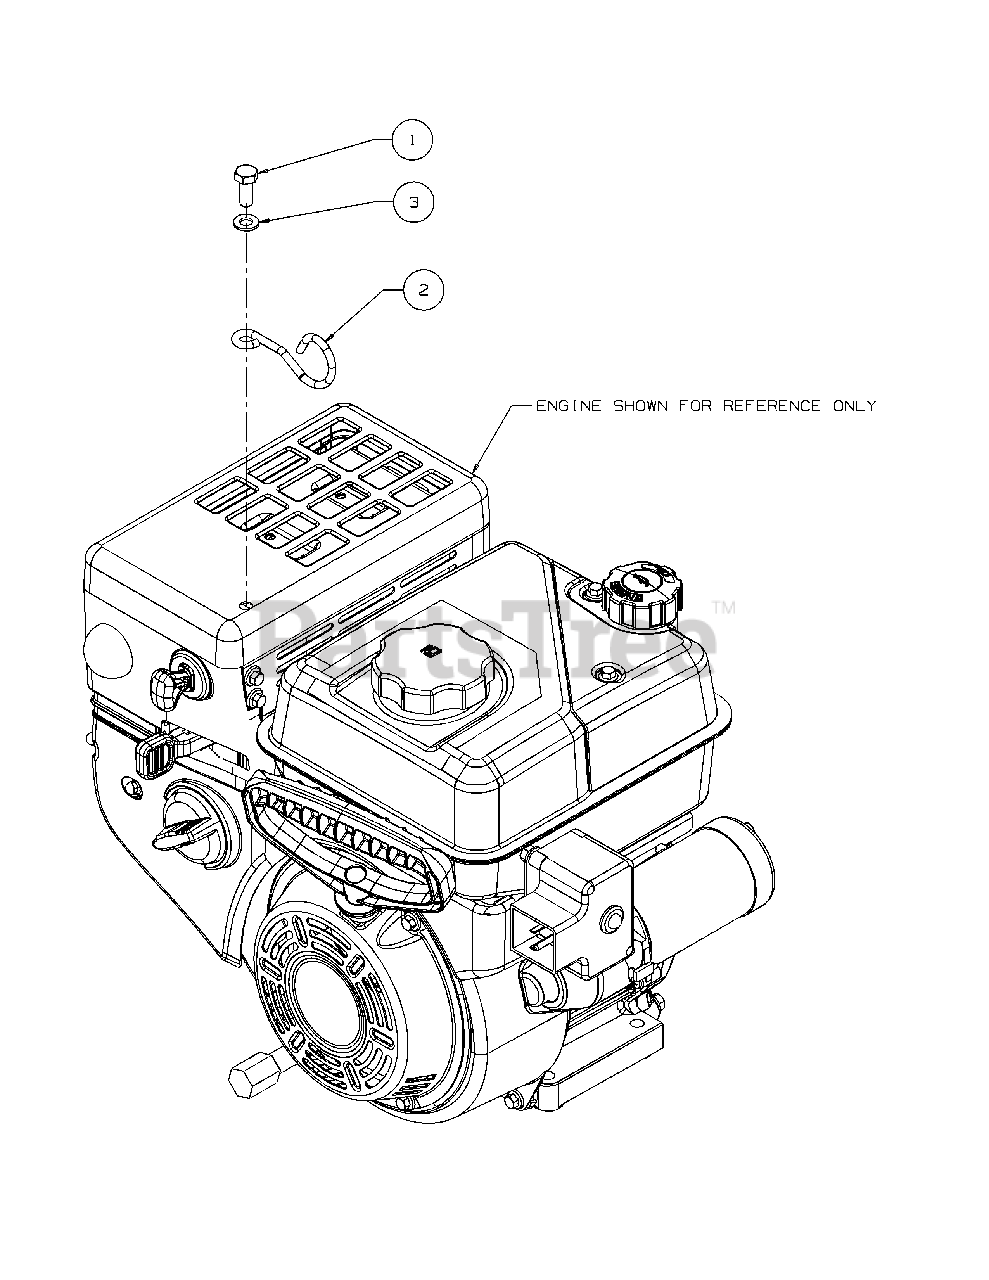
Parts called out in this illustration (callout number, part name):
1	Screw-Hex Cap M
2	Guide-Cable
3	Washer-Fl .344 X
